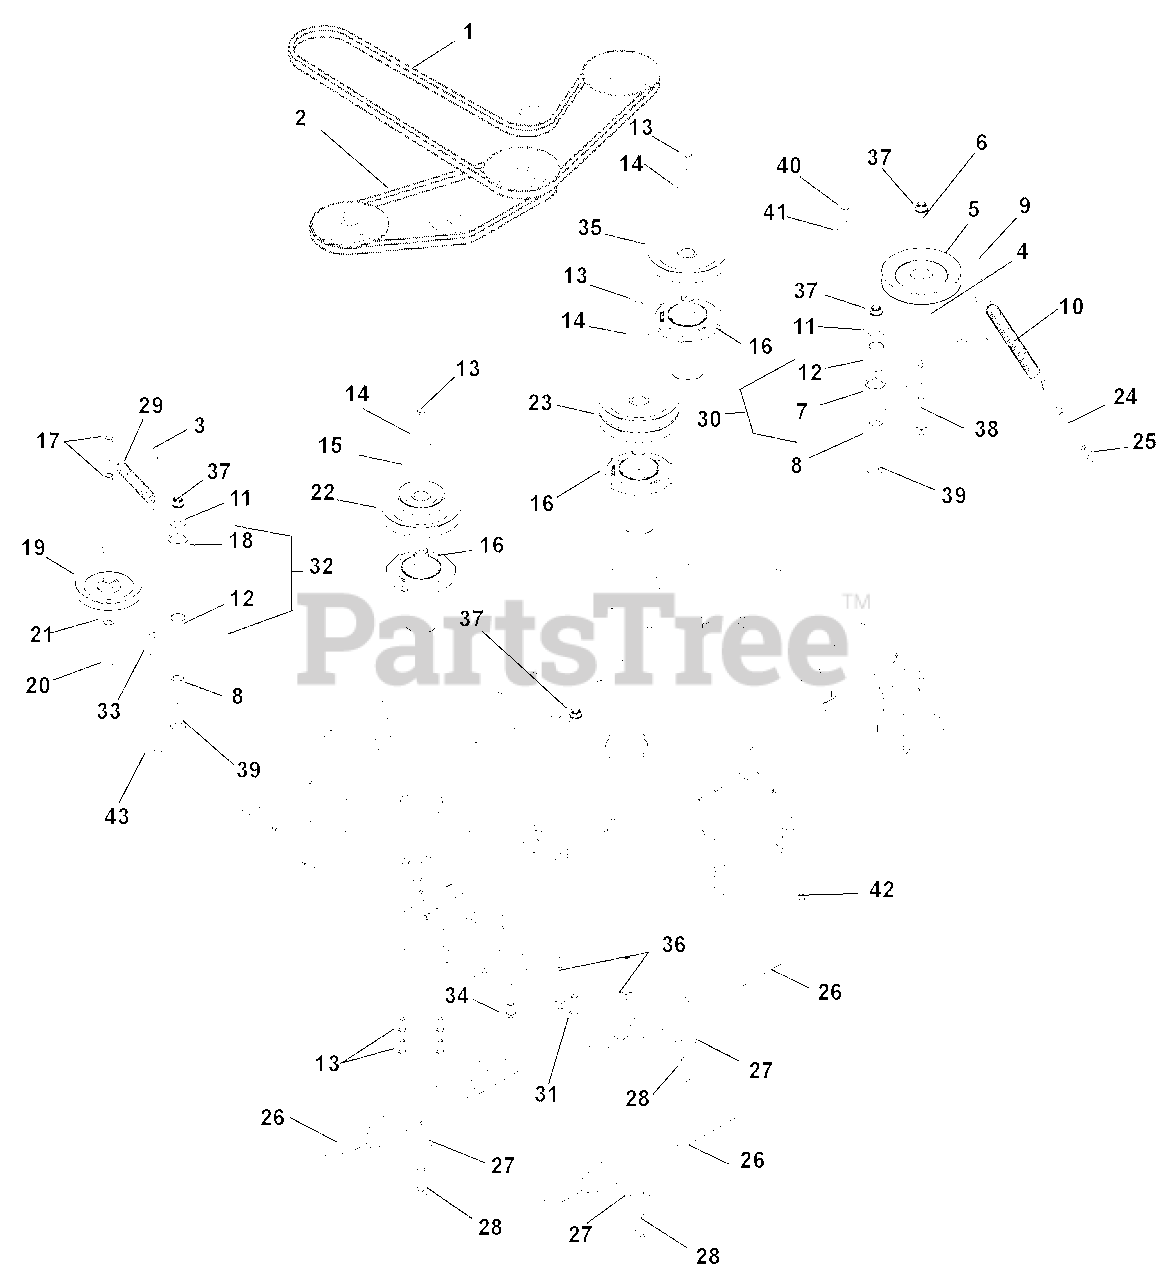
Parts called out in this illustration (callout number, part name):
1	Belt, BB 114.50 Wrapped Hex (PTO Belt) (991082)
1	Belt, BB 120.50 Wrapped Hex (PTO Belt) (991090)
2	Belt, B 51.18 Raw Cogged (Deck Belt)
3	Bolt, Hex .38-16 x 1.50 Grade 5
4	Bushing, Spacer .502 x .997 x .50
5	Sheave, .50" ID x 6.00" OD V-Idler
6	Cap, Idler Bearing Sealing
7	Idler Pivot Arm Weldment – Black
8	Bushing, Spacer .505/.500 x .999/.996 x 2.05/2.03
9	Bolt, Shoulder EP .38-16 x .30 Hex
10	Spring, Extension (PTO Deck Idler)
11	Washer, Flat Steel .563 x 1.38 x .109
12	Bushing, 1.00 x 1.125 x 1.936
13	Bolt, Hex .38-16 x 1.00
14	Washer, Flat Steel .406 x 1.50 x .245
15	Key, Square .25 x .25 x 1 RC 40-50
16	Spindle Assembly
17	Nut, Locking Center .38-16
18	Idler, Pivot Arm
19	Sheave, .38" ID x 5" OD V-Idler
20	Bolt, Hex .38-16 x 2.25
21	Washer, Flat Steel .406 x .812 x .065
22	Pulley, Double 1" ID x 5.75" & 3.50" OD
23	Pulley, Double 1" ID x 5.75" OD
24	Bolt, .38-16 x 4.00 .62 Diameter Eye
25	Nut, Hex Jam .375-16
26	Blade, 16.19" Mower
27	Washer, Bellville .63 x 1.625 x.14
28	Bolt, Hex .62-18 x 1.75 Grade 8
29	Spring, Extension (Deck Belt Idler)
30	Assembly, PTO Idler Pivot Arm (Includes item 7 and item 12)
31	Bolt, Round Head Square Neck .50-13 x 1.5, Full Thread, Grade 5
32	Assembly, Idler Pivot Arm (Includes item 12 and item 18)
33	Nut, Coupling .375-16 x 1.75
34	Bolt, Round Head Square Neck .38-16 x 1.00
35	Sheave, Single 1.0" ID x 5.75" OD
36	Bolt, Round Head Square Neck .50-13 x 3.50
37	Nut .50-13 Nyloc Flange
38	Bolt, Round Head Square Neck .50-13 x 3.00 Grade 5
39	Washer, Flat .640 x 1.75 x .250
40	Bolt, Hex .38-16 x 2.75 Grade 5
41	Nut, Hex .38-16
42	Nut, Locking Center Jam .375-16
43	Washer, Flat Steel .531 x 1.06 x .095 YZotes
